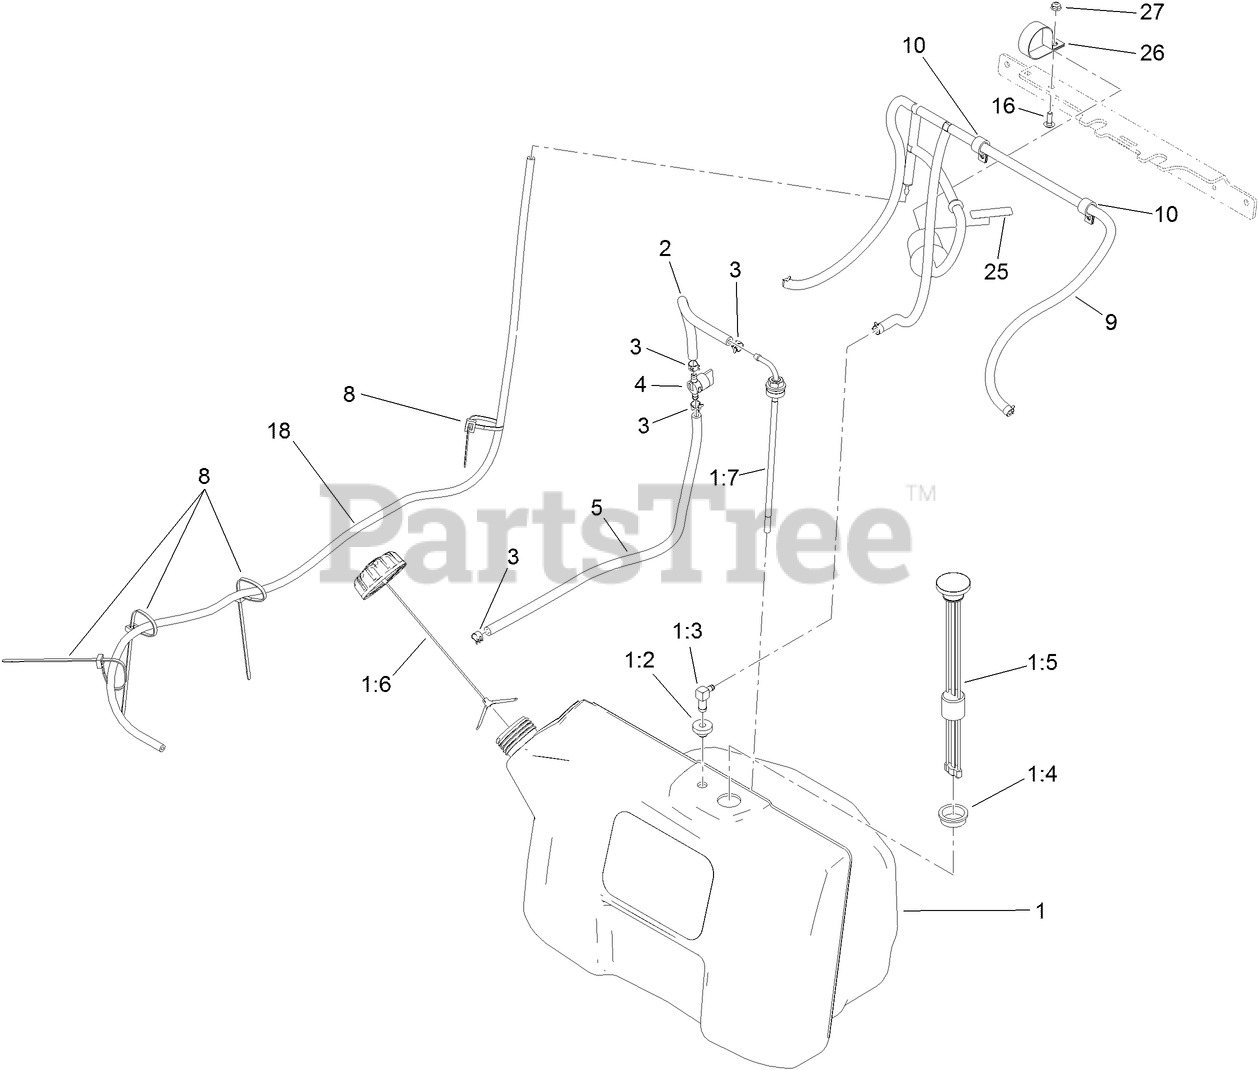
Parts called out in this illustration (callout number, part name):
1	TANK ASM
1:2	BUSHING
1:3	ELBOW-90 DEG
1:4	GROMMET
1:5	GUAGE-FUEL
1:6	CAP-FUEL, RATCHETING
1:7	FITTING-FUEL, BULKHEAD
2	HOSE-FUEL
3	CLAMP-HOSE
4	VALVE-FUEL
5	HOSE-FUEL
8	TIE-CABLE
9	VENT HOSE ASM
10	CLAMP-CABLE
16	BOLT-CARR
18	HOSE-FUEL
25	DECAL-FILTER, EMISSIONS
26	CLAMP-R
27	NUT-HF
